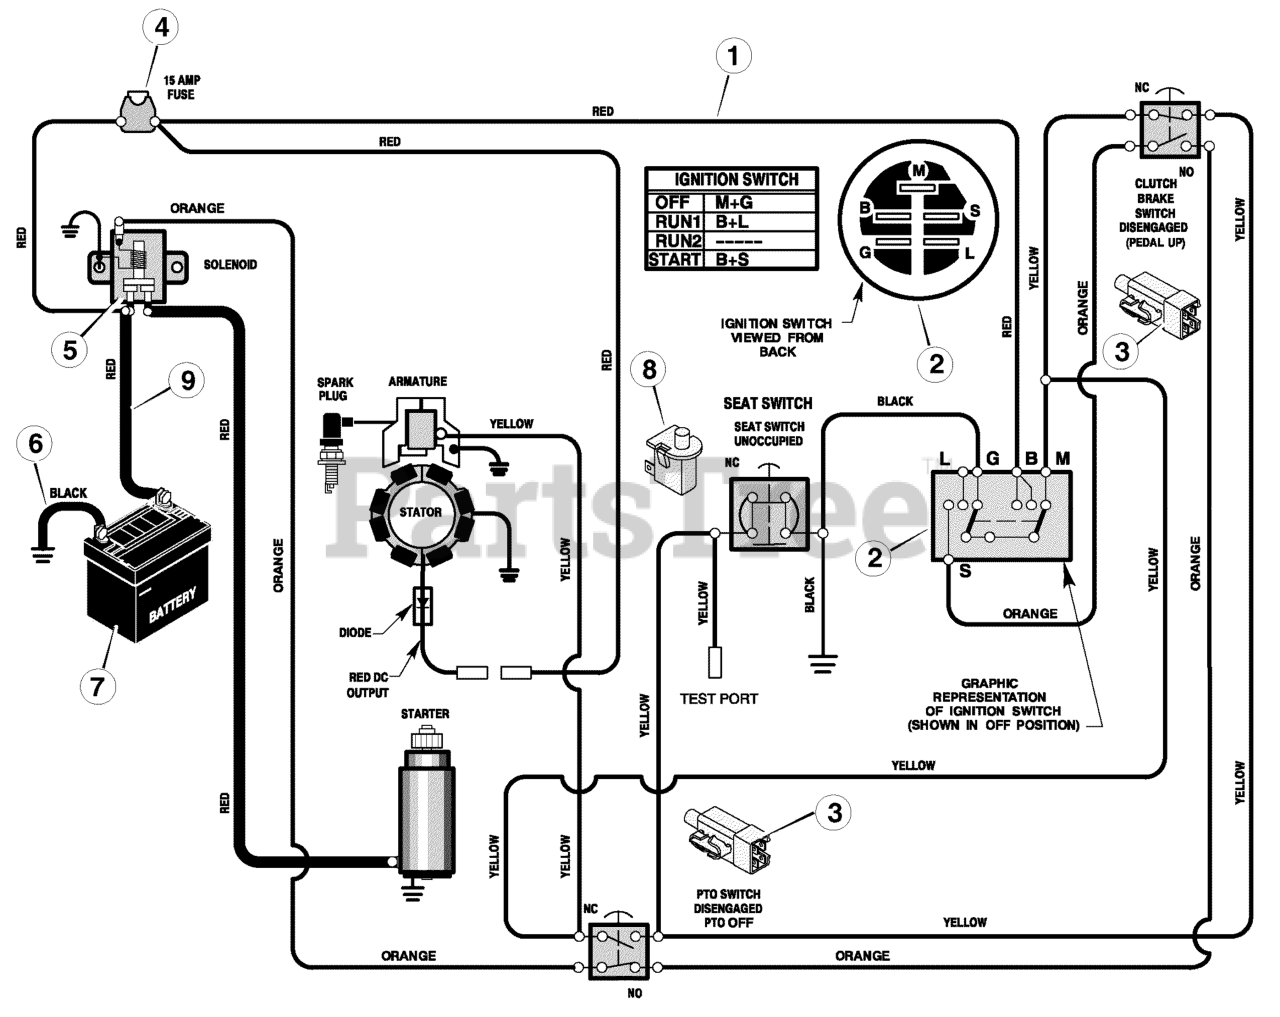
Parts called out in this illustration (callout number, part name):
1	Harness, Chassis Wire
2	Switch, Ignition
2	Key, Ignition
3	Switch, Limit
4	Fuse
4	Holder, Fuse
5	Solenoid
5	Screw, Mounting
5	Locknut
6	Cable, Battery Ground
6	Screw, Ground Cable
7	Battery
7	Bolt, Carriage
7	Wingnut
8	Switch, Seat Sensor
8	Bolt, Carriage
8	Wingnut
9	Cable, Red Battery
9	BOOT, Battery Terminal, Positive
